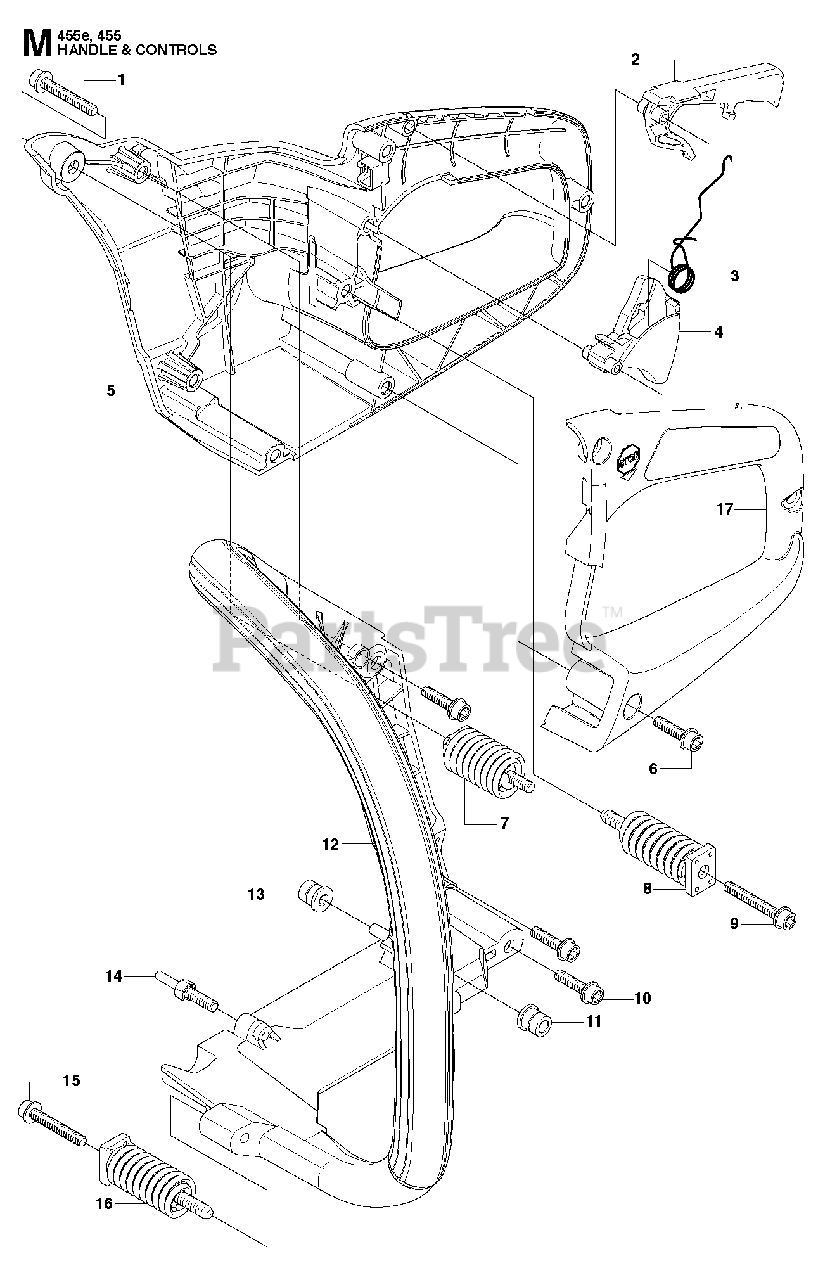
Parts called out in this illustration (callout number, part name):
2	THROTTLE LOCK
4	THROTTLE TRIGGER
5	RP HANDLE HALF, RIGHT
7	VIBRATIONS ABSORBER
8	VIBRATION ABSORBER
11	MOVEMENT LIMITER
12	FRONT HANDLE
13	MOVEMENT LIMITER
17	CAP - LEFT HANDLE
